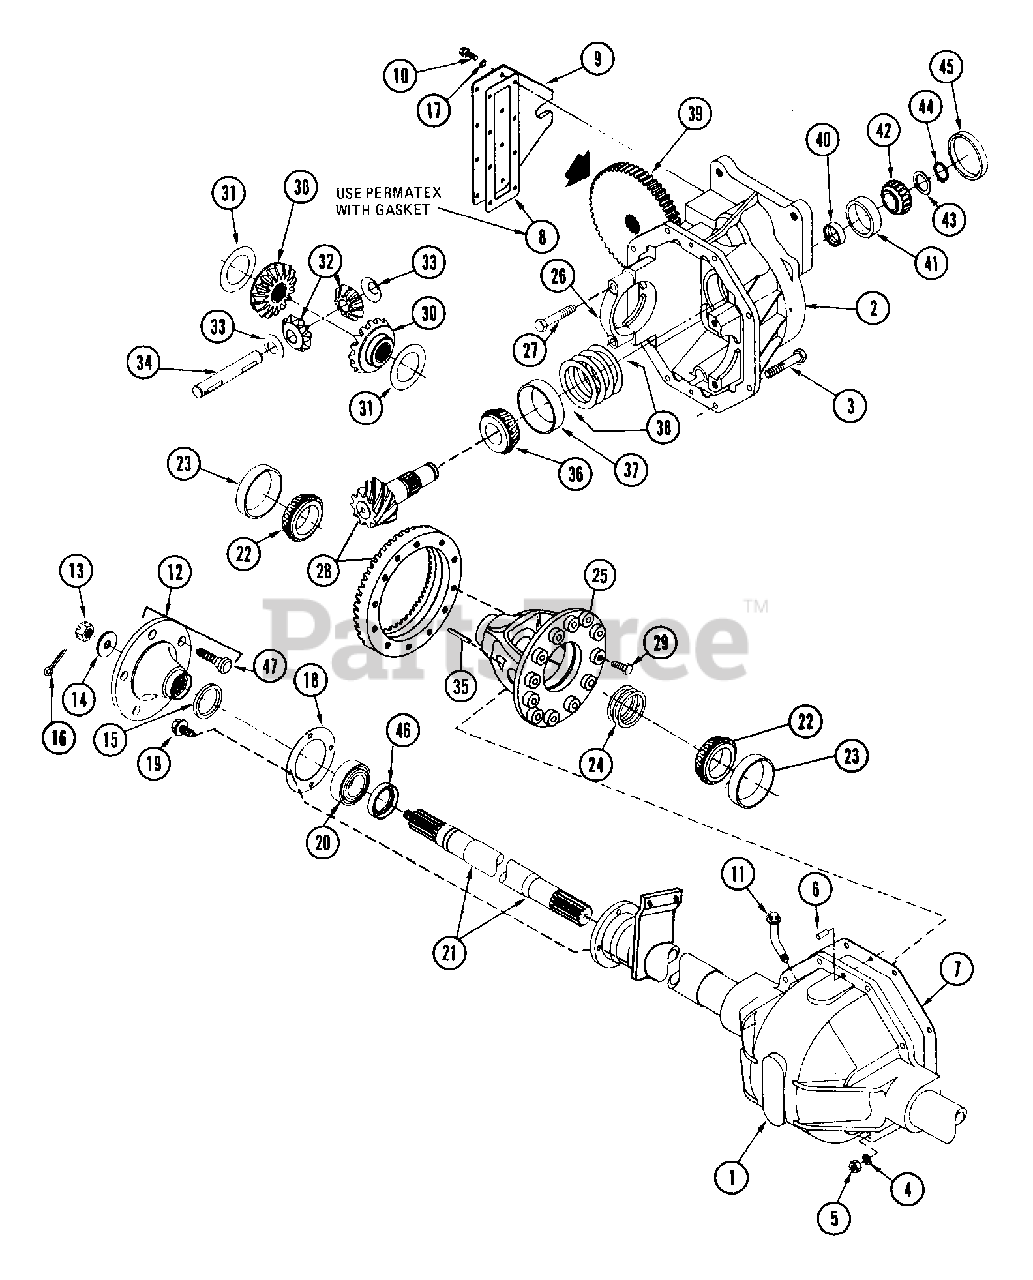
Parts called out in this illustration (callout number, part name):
1	LOWER HOUSING
2	FRONT HOUSING W/BEARING CAP &
3	BLT-HEX .31-18X1.00 PL GR5
4	WSHR-LK-INT .313X.030 PL
5	NUT-HEX .312-18
6	DOWEL PIN
9	LOCK PIN GUIDE
10	SCR-TAP 12-24X.50 HWH PL TR
11	VENT TUBE ASSEMBLY
12	SHAFT FLANGE ASSEMBLY
13	NUT-SL .875-14
14	WSHR-FL-STL .875X1.500X.1196
15	FELT SEAL
16	PIN-COTR .15X1.50
17	WSHR-LK-EXT 12X.025 PL
18	GASKET-SEE LETTER L-307
19	BLT-SERHFWH .31-18X.75 PL
20	BRG-CONE 46MMX17MM
21	AXLE SHAFT L H
21	AXLE SHAFT R H
22	BRG-CONE 1.63X.78
23	BRG-CUP 2.892X.580
25	DIFFERENTIAL CASE
26	BEARING CAP
28	RING & PINION GEAR SET
29	BLT .38-24X.812 DANA
30	SIDE GEAR
31	WSHR-FL-STL 1.578X2.375X.031
32	BEVEL GEAR
33	WSHR-BLVL .703X1.593X.031
34	PINION SHAFT
35	LOCK PIN
36	BRG-CONE 1.03X1.0013
37	BRG-CUP 2.615X.750
39	SPUR GEAR
40	FRONT PINION BEARING SPACER
41	BRG-CUP 1.968X.550
42	BRG-CONE .875X.72
43	SHIM PACK ASSEMBLY
44	RG-RTNG-EXT .875X.042
45	CUP PLUG
46	SEAL 1.183X1.183X.265
47	BLT-WHL-LUG .44-20X1.38 DANA
